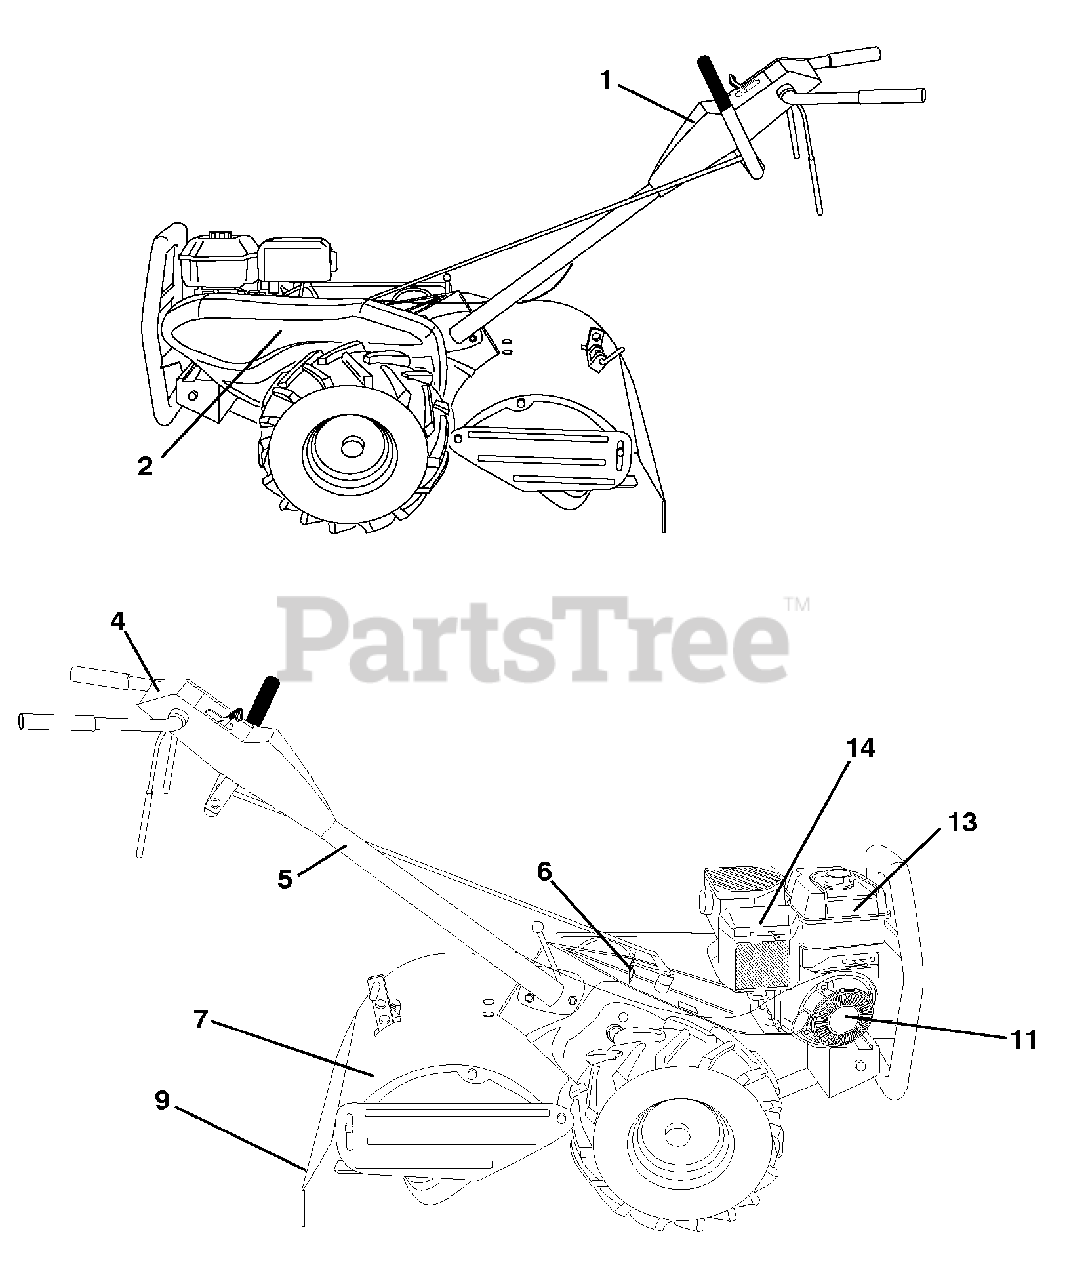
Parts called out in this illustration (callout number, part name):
1	Decal, CNTRL PNL
2	Decal, Decal, Blt Grd
4	Decal, Instruction, Tilling
5	Decal, Hand Placement
6	Decal, Shift Indicator
7	Decal, Warning, Shield
9	Decal, Warning, Rotating Tines
11	Decal, Rewind
13	Decal, Warning, Spark Arrestor
14	Decal, B&S, Air Cleaner
14	Manual, Operator's, English/French
14	Manual, Repair Parts, English/French
